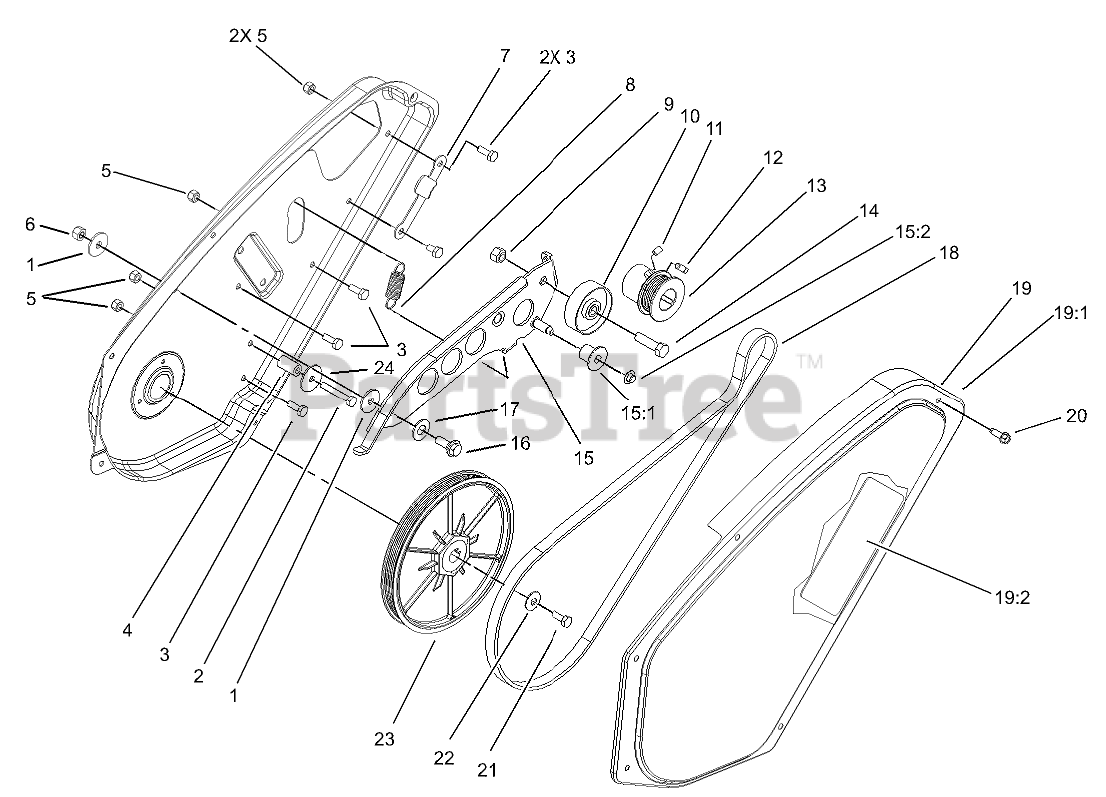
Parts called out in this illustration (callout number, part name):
1	WASHER-PIVOT
2	SCREW-HH
3	SCREW-HH
4	SLEEVE-GUIDE, BELT
5	NUT-LOCK, NI
6	NUT-LOCK, NI
7	BELT-GUIDE
8	SPRING
9	NUT-LOCK, CONE
10	PULLEY-IDLER
11	SCREW-HSH
12	SCREW-SQH
13	PULLEY
14	SCREW-HH
15	BRAKE-ARM
15:1	ROLLER-BRAKE
15:2	NUT-PUSH
16	SCREW-SHOULDER
17	WASHER
18	BELT-DRIVE
19	DRIVE COVER ASM
19:1	DECAL-WARNING
19:2	DECAL-ROUTING, BELT
20	SCREW-HWHTF
21	SCREW-HH
22	WASHER-BELLEVILLE
23	PULLEY-ROTOR
24	WASHER-FLAT
